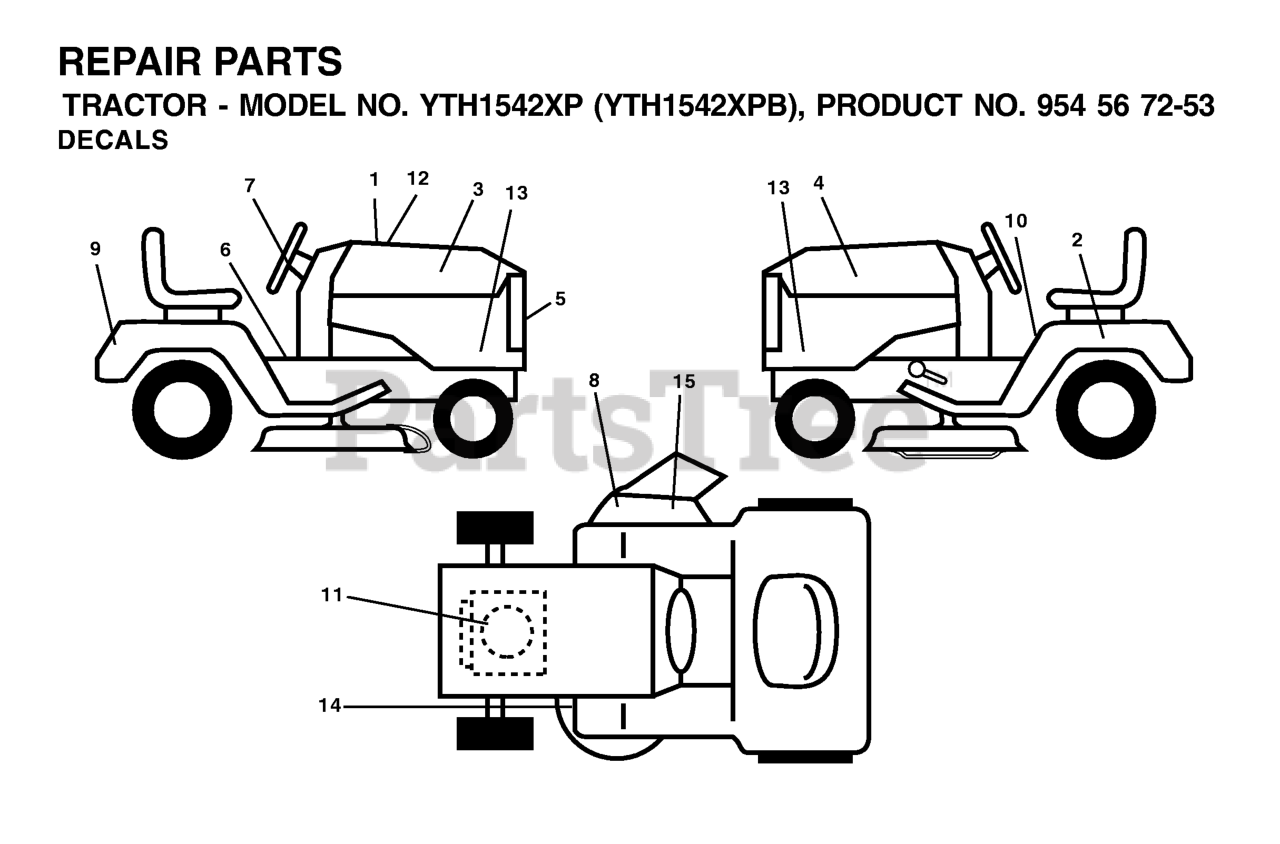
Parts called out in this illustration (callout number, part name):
1	DECAL HOOD CUST. RESP.
2	DECAL BTRY SYMBOLS
5	DECAL.GRILLE.HUSQ
7	DECAL.WHEEL.STEERING.HUSQ.PERM
8	DECAL.WARN.KEEP.HAND.AWAY
9	DECAL, FENDER
10	DECAL FENDER DANGER
13	DECAL HOOD SIDES
14	DECAL V BELT SCHEMATIC
15	DECAL DECK "B" 42"
